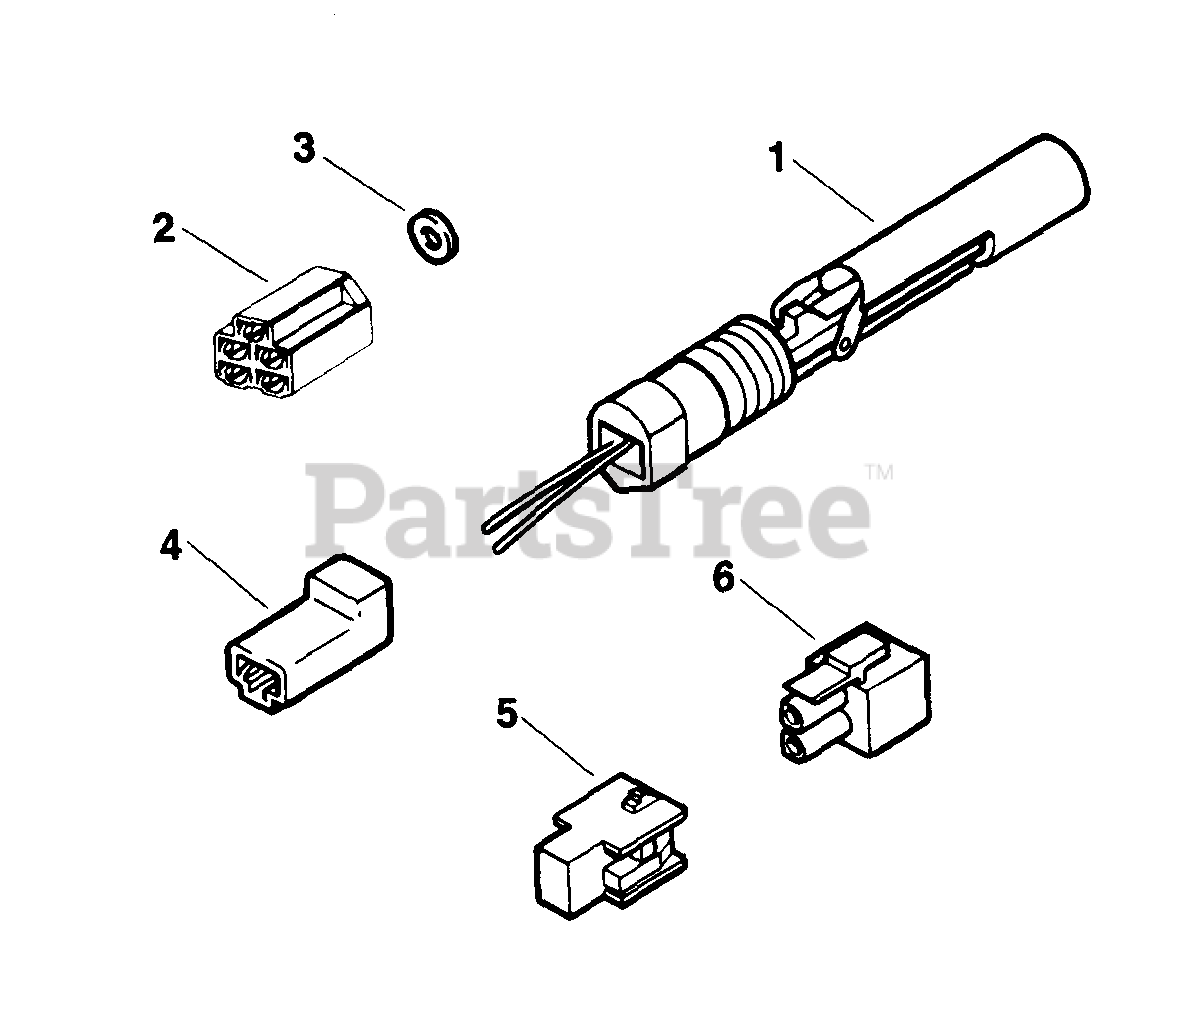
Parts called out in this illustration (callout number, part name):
1	KIT, OIL LEVEL SWITCH
5	CONNECTOR - DISCONTINUED
6	CONNECTOR - DISCONTINUED
